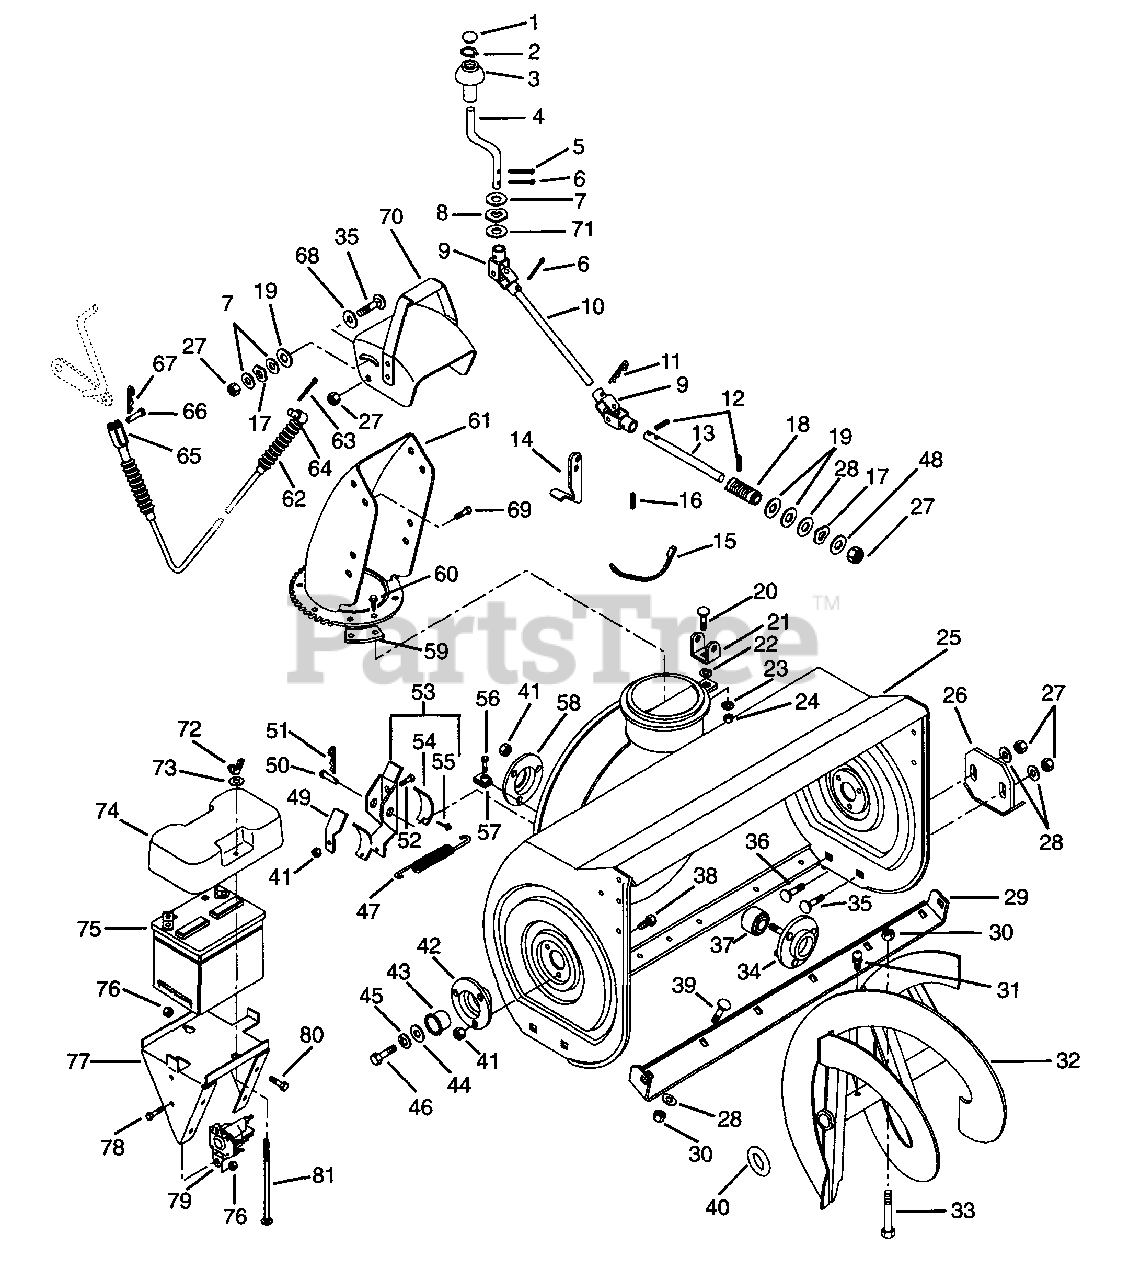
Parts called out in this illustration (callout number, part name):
1	HOLE PLUG
2	RG-RTNG-EXT .375X.010
4	CRANK, CHUTE
5	@PIN-CTR .12X.75 EXTPRSQCT YWZ
6	@PIN-CTR .12X1.00 EXTPRSQCT YZ
7	@WSHR-FL-STL.406X.812X.065 YWZ
8	SPRING WASHER
9	UNIVERSAL JOINT ASS'Y
10	ROD, CHUTE CRANK
11	PIN-HAIR INT .08X.38X1.42 YWZC
12	PIN-ROLL .125X.75
13	SHAFT, WORM
14	SUPPORT, CHUTE CRANK
15	CABLE TIE LG 8-7/8
16	TRIM
17	WAVE WASHER .406X.750X.063FH
18	WORM GEAR L.H.
19	WSHR-PLASTIC .390X.875X.062
20	@BLT-RHDSSQNK .31-18X.75 G5YZ
21	WORM CLEVIS
22	@WSHR-LK-EXT.326X.599X.031YWZC
23	WSHR-LK PYM .31X.062YWZC
24	@NUT-HEX .31-18 YWZC
25	HOUSING, BLOWER 24"
25	HOUSING, 24" BLOWER W/DECALS
25	HOUSING, 28" BLOWER W/DECALS
25	HOUSING, BLOWER 28" ELECTRIC
25	HOUSING, 32" BLOWER W/DECALS
25	HOUSING, BLOWER 32" ELEC.
25	HOUSING, BLOWER 36" ELECTRIC
26	RUNNER
26	RUNNER - SKID SHOE
27	@NUT-LK-CTR .38-16 YWZC
28	@WSHR-FL-STL.38X.875X.083 YWZC
29	SCRAPER BLADE 24"
29	SCRAPER BLADE 32"
29	SCRAPER BLADE 28"
29	SCRAPER BLADE 36"
29	BLADE, SCRAPER 24"
30	@NUT-LK-CTR .31-18 YWZC
31	FTG-LUBE .25-28X.256 YWZC
32	RAKE, RIGHT-32"(1ID X 15.75OD)
32	RAKE, LEFT-32"(1"ID X 15.75OD)
32	RAKE, RIGHT-24"(1ID X 14.75OD)
32	RAKE, LEFT-24"(1"ID X 14.75OD)
32	RAKE, RIGHT-28"(1ID X 15.75OD)
32	RAKE, LEFT-28"(1"ID X 15.75OD)
32	RAKE, RIGHT-36"(1ID X 15.75OD)
32	RAKE, LEFT-36"(1"ID X 15.75OD)
32	RAKE, RIGHT-24"(1ID X 15.75OD)
32	RAKE, LEFT-24"(1"ID X 15.75OD)
33	SHEAR BOLT SERVICE ASSEMBLY
34	BEARING FLANGE
35	BLT-RHHDSQSHNK .38-16X.75 G2YZ
36	@BLT-RDHDSQNK .38-16X1.00 G2YZ
37	BRG-BALL1.0X2.0X.56
37	BRG-BALL .750X1.750X.50
38	BLT-SERNK SL .25-20X.50 YWZC
39	@BLT-RHDSSQNK .31-18X.62 G5YZ
40	WSHR-FL-STL 1.010X1.505X.062YZ
41	@NUT-LK-CTR .25-20 YWZC
42	BEARING SUPPORT
43	BSHG-FLG 1.000X1.12X.62X1.50BR
44	WSHR-FL-STL.511X1.441X.125 YWZ
45	@WSHR-LK .50X.125 REG YWZC
46	@BLT-HEX .50-13X1.00 GR5 YWZC
47	SG-TENS .062X.56X8.0 WLD 11
48	WSHR,FLT .438X1.00X.160 ZCC
49	ARM EXTENSION
50	PIN-CLEV .371X1.16 YWZC
51	@PIN-CTR .06X.75 EXTPRSQCT YWZ
52	@BLT-HEX .25-20X.75 GR5 YWZC
53	BRAKE ARM ASSEMBLY
54	BRAKE LINING
55	RVT-TBLR .187X.437 RH ST PL
56	BLT-SERHFWH .38-16X.75 YWZC
57	NUT-RETNR .38-16 TINRMAN
58	BEARING FLANGE
59	CHUTE CLAMP
60	@SCR-TAP 12-24X.50 HWH TR YWZC
61	DISCHARGE CHUTE - HIGH
61	DISCHARGE CHUTE
62	CONTROL CABLE
63	@PIN-CTR .09X.75 EXTPRSQCT YWZ
64	PIVOT
65	CLEVIS
66	CLEVIS PIN
67	@PIN-CTR .06X.50 EXTPRSQCT YWZ
68	@WSHR-FL-STL.406X.812X.065 YWZ
69	@BLT-HEX .38-16X.75 GR5 YWZC
70	CHUTE DEFLECTOR W/DECAL
70	DEFLECTOR W/DECAL
71	WSHR-FL-STL .382X.812X.023YWZC
72	NUT-LK WING .250-20 YWZC
73	@WSHR-FL-STL.281X.62X.065 YWZC
74	COVER, BATTERY
75	BATTERY
76	@NUT-LK-CTR .25-20 YWZC
77	TRAY, BATTERY
78	BLT-HEX .25-20X.63
79	SOLENOID
80	@BLT-HEX .25-20X.75 GR5 YWZC
81	@BLT-RDHDSQNK .25-20X7.00 G2YZ
